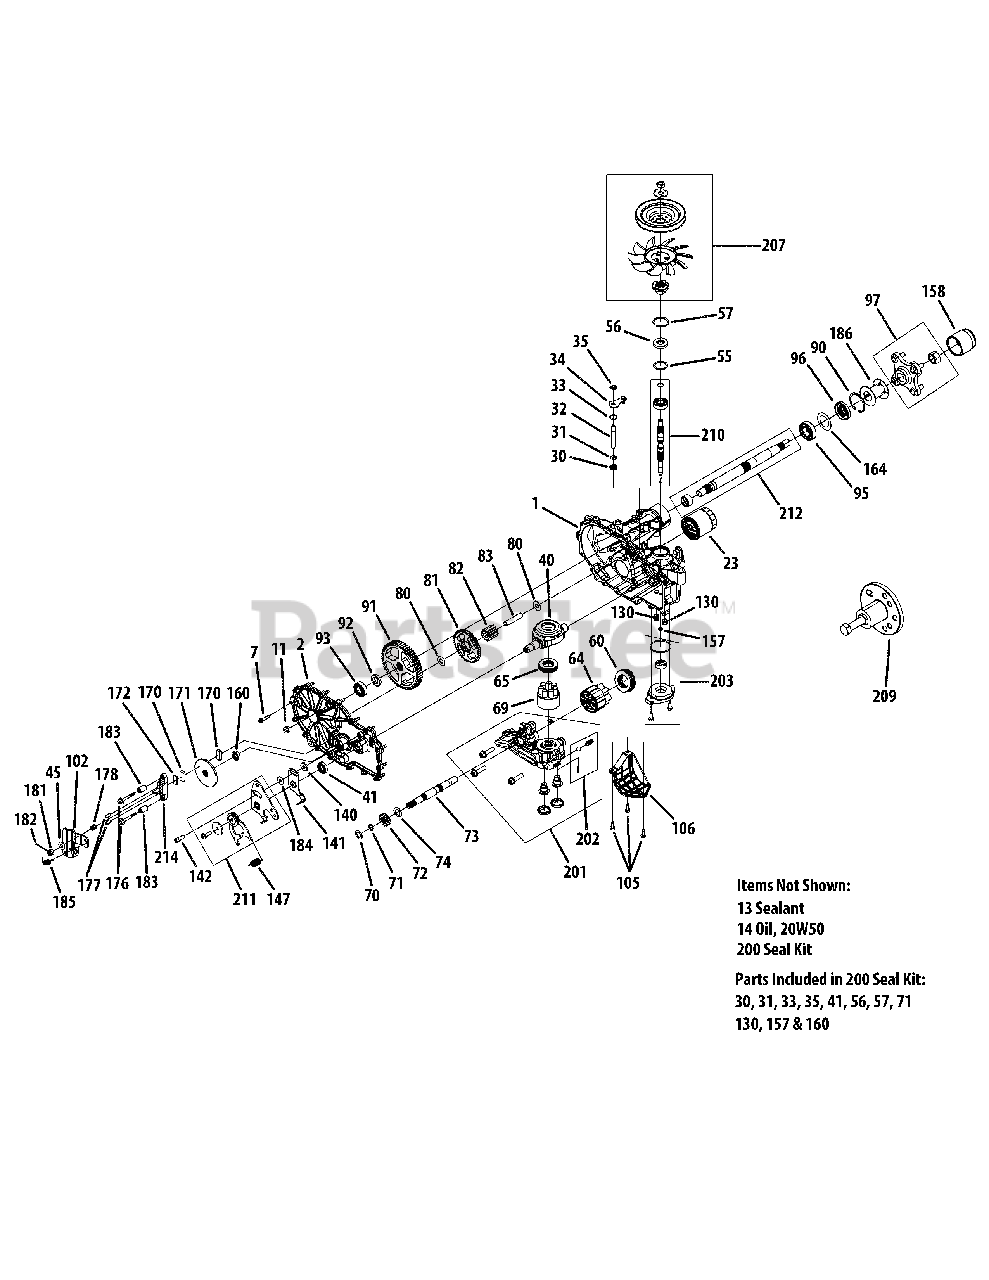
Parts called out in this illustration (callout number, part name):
1	Kit, Main Housing, LH Charge
2	Kit, Cover Side LH Control
7	Screw, Hex Washer
23	Filter, Spin-On 2.6 x 3.0
30	Seal, Lip, .375 x .75 x .25
31	Ring, Retaining .375 External
32	Rod, Bypass
33	Ring Retaining .750 Internal
34	Arm, Bypass
35	Ring, Ret .375 External
40	Trunnion, Swashplate
41	Seal, Lip 18 x 32 x 7
45	Washer, .34 x .88 x .06
55	Washer, 1.23 x 1.57 x .04
56	Seal, Lip 17 x 40 x 7
57	Ring Retaining Internal
60	Bearing, Thrust 35 x 62 x 18
64	Kit, 16cc Cylinder Block Assembly
65	Thrust Bearing, 30 x 52 x 13
69	Kit, Block, 7 Piston
70	Washer, .63 x 1.00 x .05
71	Ring, Reatining, Motor Shaft
72	Gear, 14T (Steel)
73	Shaft, Motor
74	Washer, .71 x 1.16 x .04
81	Gear, 45T
82	Gear, 11T (Steel)
83	Pin, Jackshaft
90	Ring, Retaining 2.25 Internal
91	Gear, 54T
92	Spacer, .750 x 1.00 x .257
93	Bearing, Ball 3/4 x 40mm x 12mm
95	Bearing, Ball 25.4 x 52 x 15
96	Seal, Lip, 1.0 x 2.06 x .38
97	Kit, Hub 4-Bolt
102	Arm, Brake
105	Screw, Hex Washer 1/4-20 x .75
106	Guard, Filter, LH
130	Tube, Charge Triple O-Ring
140	Spacer, .320 x 1.005 x .150
141	Arm, Neutral Right
142	SHCS, 5/16-24 x 7/8 (W/Patch)
147	Spring, Extension
157	Seal, Gerotor .281 x .420 x .160
158	Cap, Axle
160	Seal, Lip .625 x 1.00 x .250
164	Spacer, 1.355 x 2.035 x .021
170	Puck, Brake
171	Rotor, Brake
172	Puck, Plate
176	Screw .250-20 x 2.0 HFS Patch
177	Pin, Brake Actuating
178	Compression Spring
181	Nut, Castle 5/16-24
182	Pin, Cotter 3/32 x 3/4
184	Washer, .34 x .88 x .06
185	Spring, Brake Arm Bias
186	Tube, Axle 2.03
200	Kit. Seal, ZT-2800
201	Kit, Center Section LH Charge
202	Kit, Charge Relief
203	Kit, Charge
207	Kit, Fan Pulley
207	Fan Only
207	Pulley Hub
209	Kit, Hub Puller
210	Kit, Input Shaft
211	Kit, RTN Bidirectional
212	Kit, Shaft Axle
214	Kit, Brake Yoke
